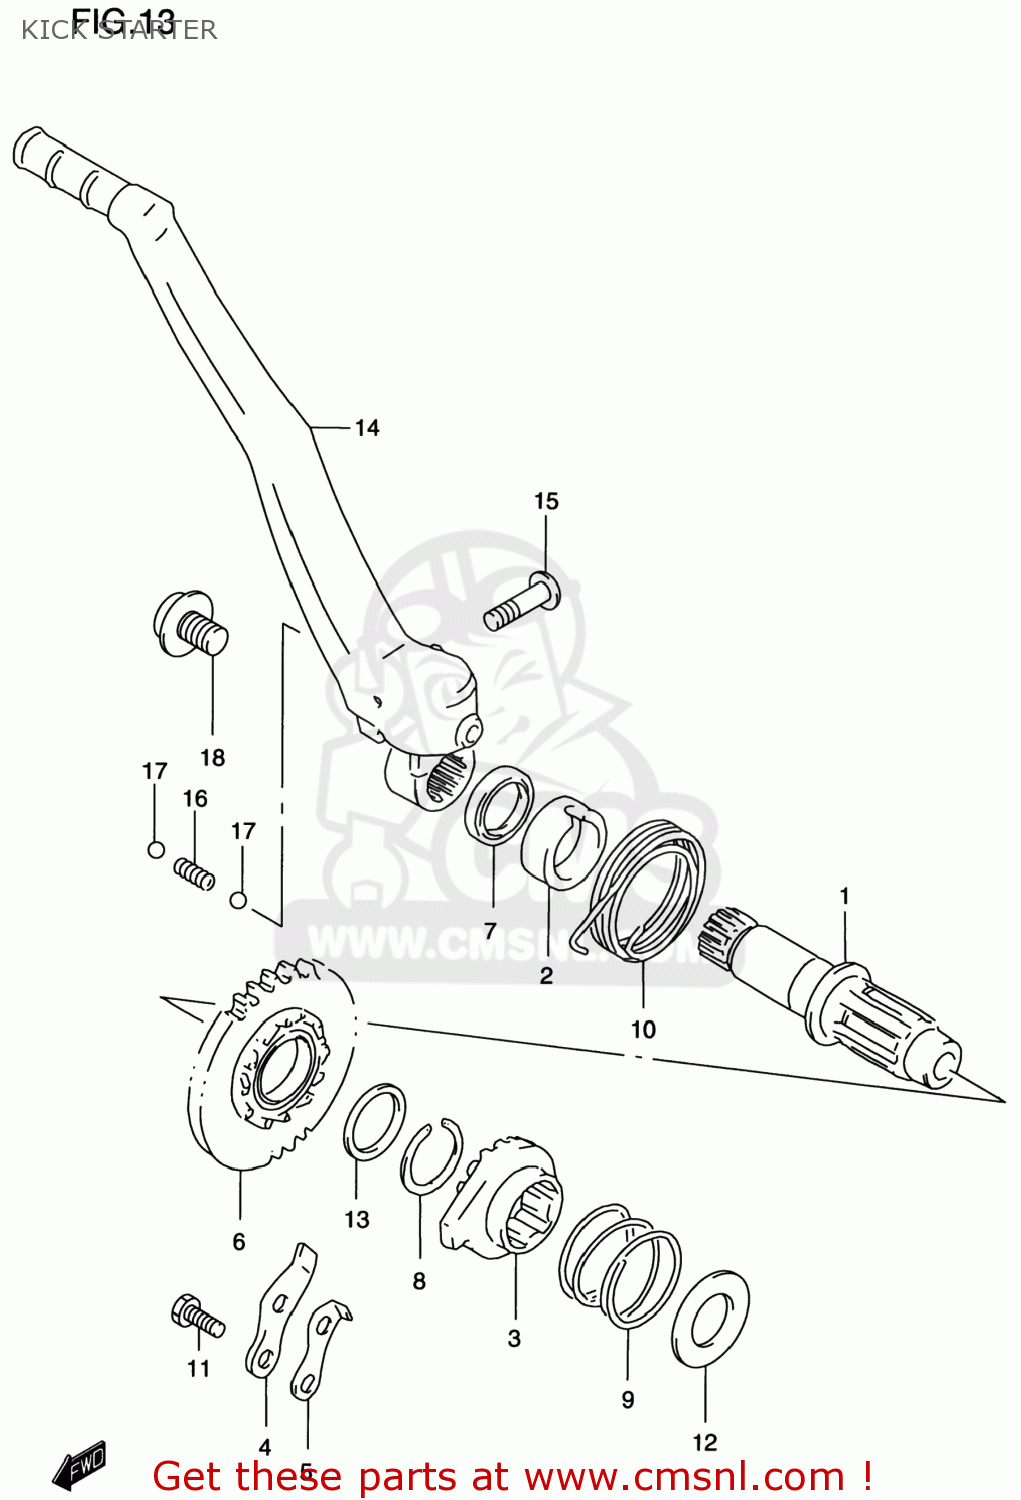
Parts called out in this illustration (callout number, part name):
1	SHAFT,KICK STARTER
2	GUIDE,KICK STARTER SHAFT
3	STARTER,KICK
4	GUIDE,KICK STARTER
5	STOPPER,KICK STARTER
6	GEAR,KICK STARTER DRIVE(NT:28)
7	SEAL,OIL(20X27X5)
8	CIRCLIP
9	SPRING
10	SPRING
11	BOLT
12	WASHER
13	SHIM
14	LEVER ASSEMBLY,KICK STARTER
15	SCREW(6X27.5)
16	SPRING
17	BALL
18	BOLT(8X14)
